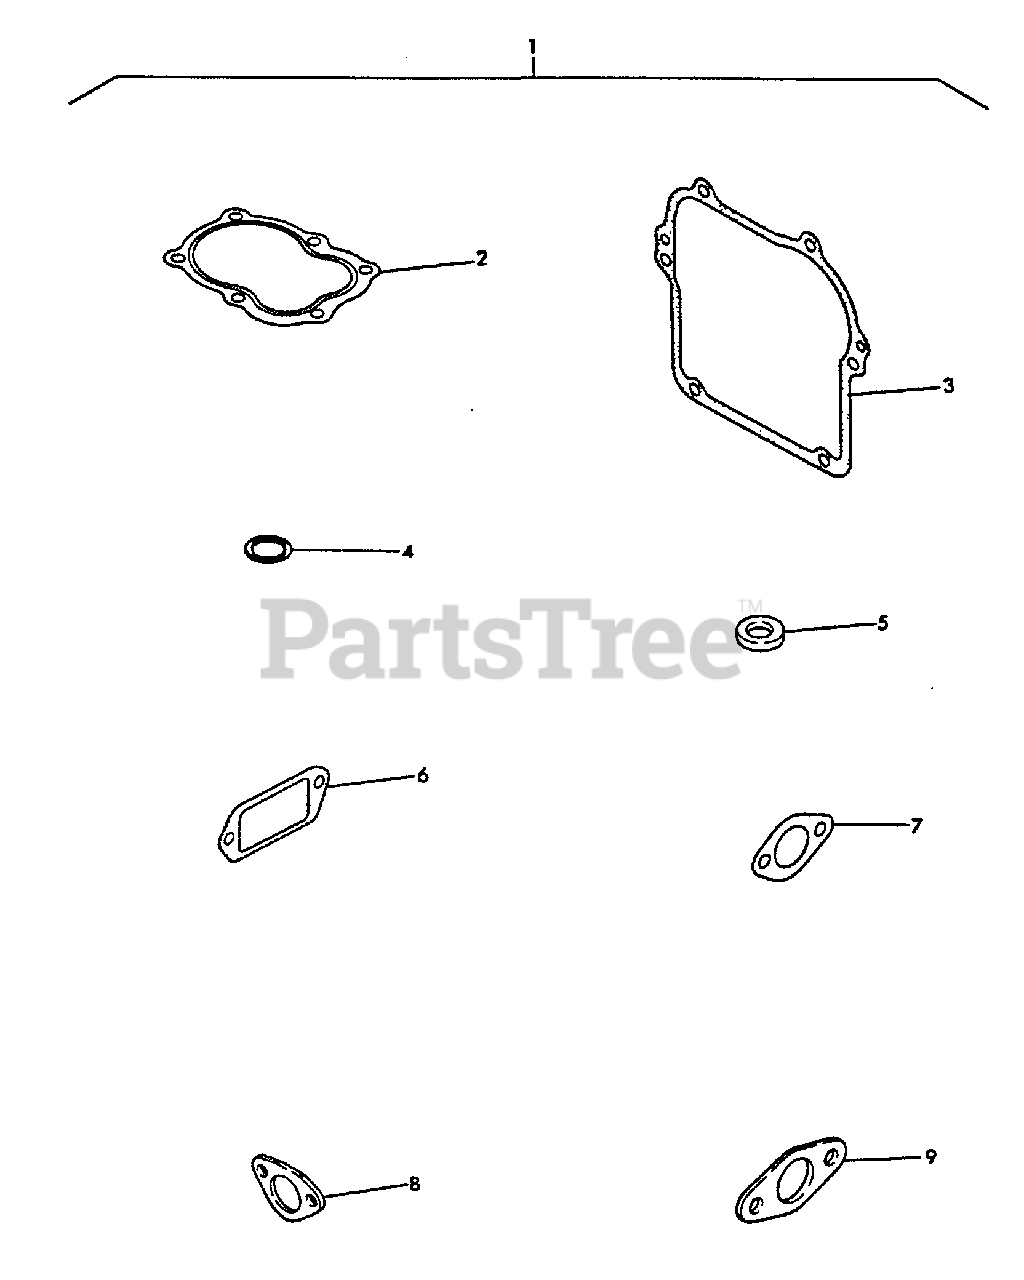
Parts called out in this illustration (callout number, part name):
1	GASKET KIT
2	GASKET, CYLINDER
3	GASKET, CRANKCASE
4	O-RING 1A P-15.0
5	GASKET
6	GASKET, BREATHER
7	GASKET
8	GASKET, EXHAUST
9	GASKET, INTAKE
